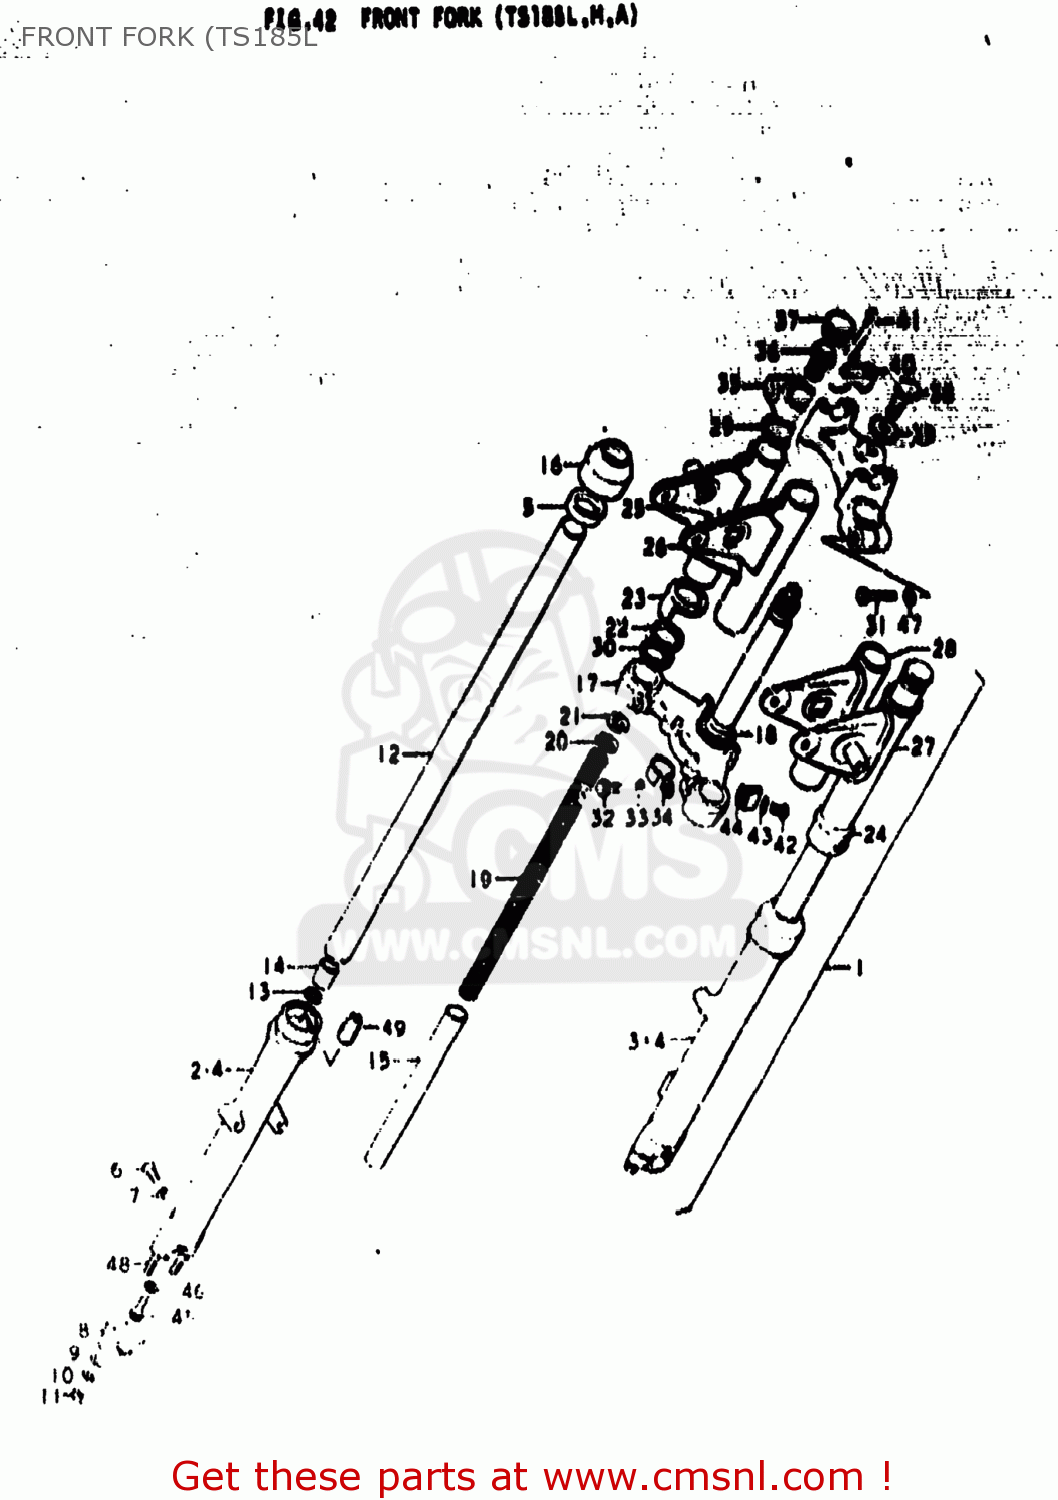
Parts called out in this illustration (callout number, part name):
1	DAMPER SET
2	TUBE,OUTER,RIGHT
3	TUBE,OUTER,LEFT
4	TUBE,OUTER,LEFT
5	SEAL,OIL
6	SCREW
7	GASKET,DRAIN,PLUG (NAS)
8	HOLDER,AXLE
9	WASHER
10	LOCK WASHER
11	NUT (8MM)
12	TUBE,FORK,INNER
13	SNAP RING
14	PISTON
15	CYLINDER,FRONT FORK
16	SEAL,DUST
17	STEM,STEERING
18	RACE,STEERING OUTER LWR
19	SPRING,FRONT FORK
20	GUIDE,SPRING
21	SEAT,SPRING
22	CUSHION,HEADLAMP BRACKET
23	COVER, STEERING STEM RH
25	BRACKET,HEADLAMP HOUSING
26	BRACKET,HEADLAMP HOUSING
27	BRACKET,HEADLAMP,LEFT
28	BRACKET,HEADLAMP,LEFT
29	SEAT,HEADLAMP BRACKET
30	GUIDE, COVER
31	BOLT,FORK INNER TUBE F
32	BOLT,FORK INNER TUBE F
33	WASHER,LOCK 12
34	CLIP
35	HEAD,STEERING STEM
36	CAP
37	CAP,FRONT FORK
38	BOLT,FORK INNER TUBE
39	WASHER
40	HOLDER,HANDLEBAR
41	Bolt
42	SCREW
43	LOCK WASHER
44	CLIP
45	BOLT
46	GASKET
47	LOCK WASHER
48	BOLT,STUD
49	PIECE,OIL LOCK
